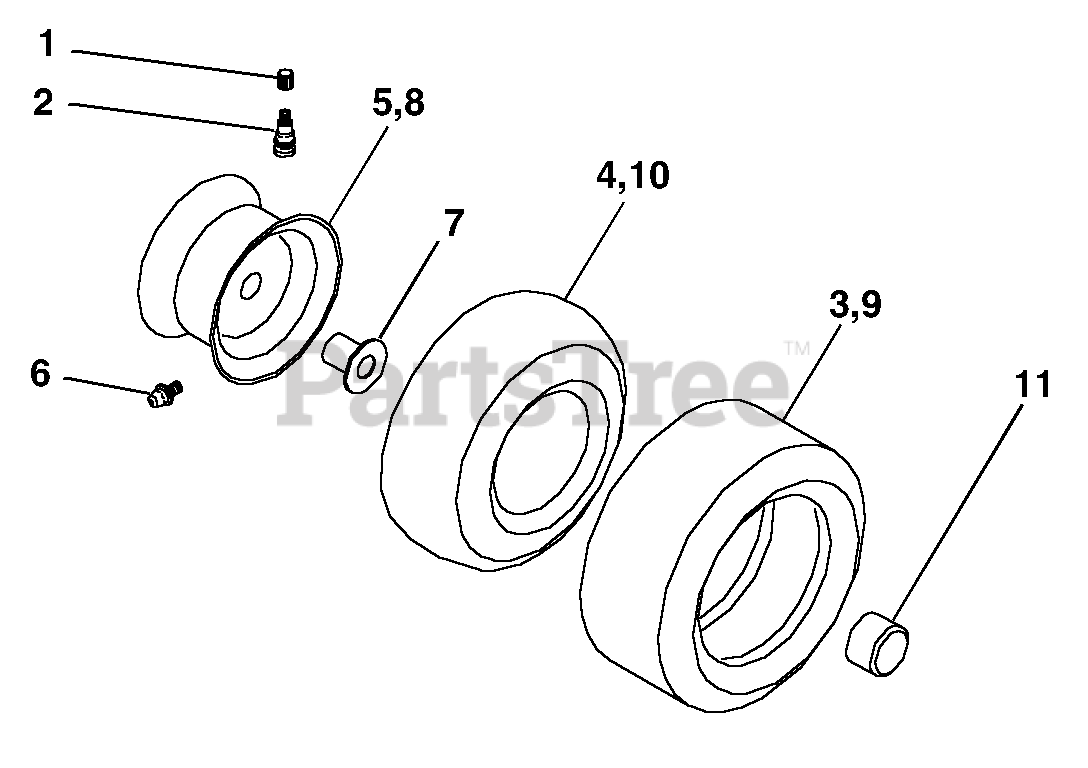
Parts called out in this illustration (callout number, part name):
1	Cap Valve Tire
2	Stem Valve
3	Tire F
4	Tube Front
5	Rim Asm 8" front
6	Fitting Grease
7	Bearing Flange
8	Rim Asm 12" rear
9	Tire Rear
10	Tube Rear
11	Cap Axle Blk 1 50 X 1 00
